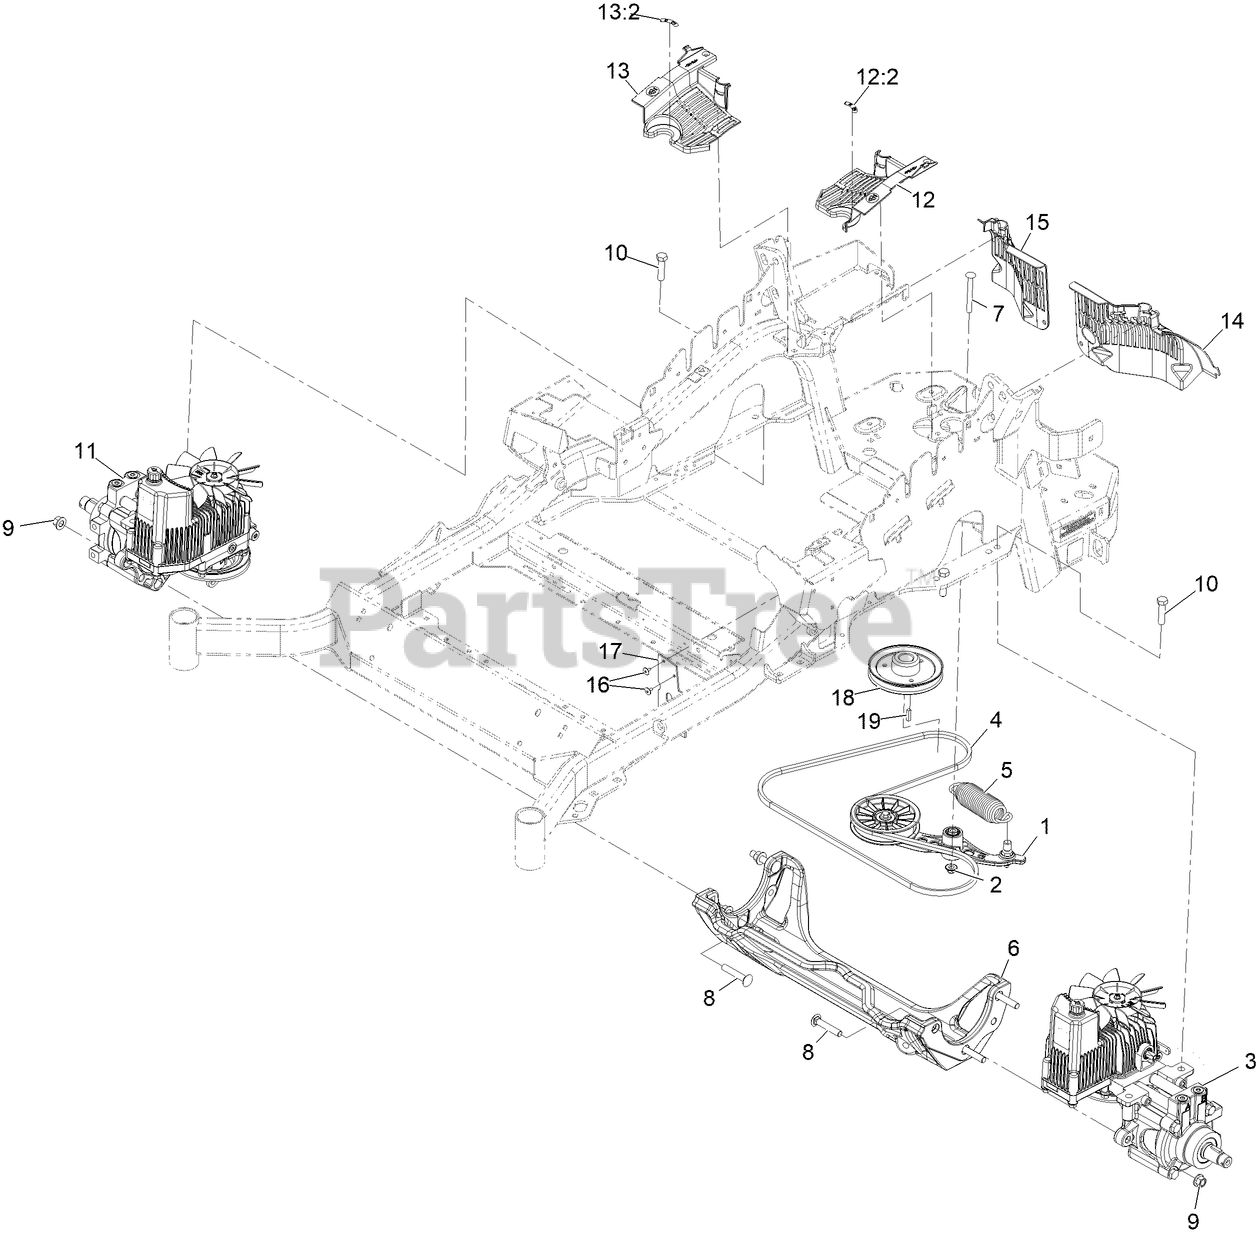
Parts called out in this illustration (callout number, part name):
1	PUMP IDLER ASM
2	Nut-Nyloc 3/8-16 Flg
3	Hydro-LH
5	SPRING-EXTENSION
6	CRADLE-HYDRO
7	BOLT-SHOULDER, CARRIAGE 3/8-16 X 3 1/2
8	SCREW-CARR
9	Nut-Lock 1/2-13
10	SCREW-HH
11	HYDRO-RH
12	LH HYDRO GUARD ASM
12:2	DECAL-OIL, HYDRO
13	RH HYDRO GUARD ASM
13:2	DECAL-OIL, HYDRO
14	GUARD-HYDRO, REAR (LH)
15	GUARD-HYDRO, REAR (RH)
16	RIVET-POP
17	DEFLECTOR-AIR FLOW
18	SHEAVE, W/HUB
